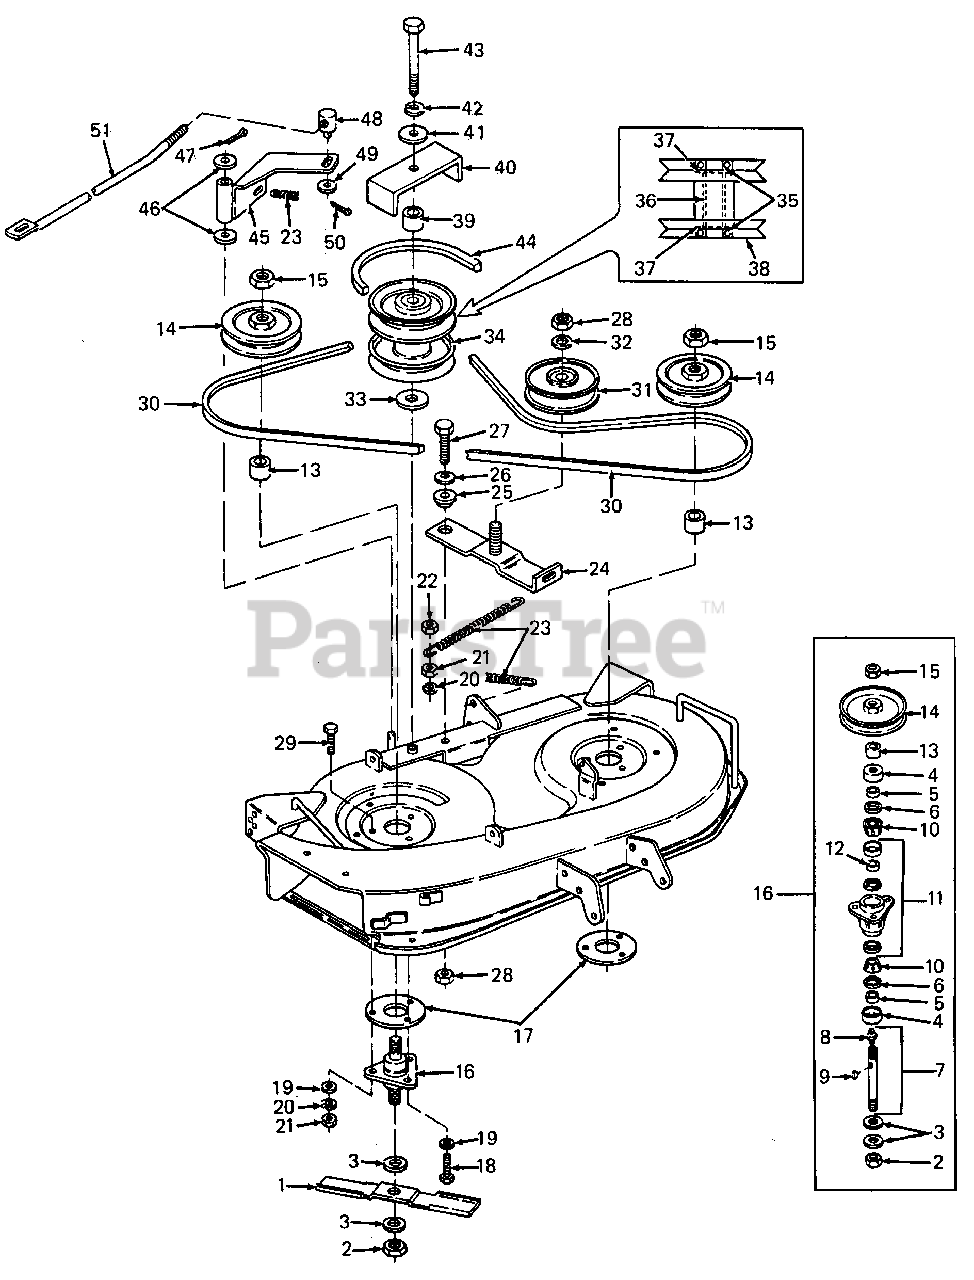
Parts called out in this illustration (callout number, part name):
1	Blade, Low Lift, 16.28 Lg
2	Nut, Hex, 3/4-16 GR8
3	Washer, Flat, .781 X 2.0 X .105 Thk HDN
4	Cup, Spindle HDN
5	Spacer, .755 X 1.25 X .44 Lg
6	Seal, Oil, 1.25 X 1.874 X .25
7	Kit, Spindle w/Seal
8	Fitting, Lube, 3/16 Drive
9	Key, #91 Woodruff, 1/4 X 3/4 HDN
10	Cone, Bearing
11	Housing, Spindle w/Cups
12	Spacer, Bearing
13	Spacer, .75 X 1.38 X .56 Lg
14	4L V-Pulley, 4.62 OD X .75 ID
15	Nut, Hex Jam, 3/4-16 GR5
16	Spindle Service Kit
17	Plate, Spindle Mounting
18	Screw, Hex Cap, 3/8-16 X 1.75 Lg GR5
19	Washer, Flat, .378 X 1.0 X .127 Thk
20	Washer, Lock, 3/8
21	Nut, Hex, 3/8-16 GR5
22	Nut, Hex Center Lock Jam, 3/8-16
23	Spring, Extension, .62 OD X 6.12 Lg
24	Bracket, Idler
25	Spacer, Shoulder
26	Washer, Bell
27	Screw, Hex Cap, 3/8-16 X 1.25 Lg GR5
28	Nut, Hex Center Lock, 3/8-16 GR5
29	Screw, Hex Cap, 3/8-16 X 1.25 Lg GR5
30	V-Belt, 1/2 X 60 Lg, A Full
31	Pulley, Flat Idler, 3.88 OD
32	Washer, Flat, .385 X .88 X .06 Thk HDN
33	Washer, Flat, .63 X 1.0 X .06 Thk HDN
34	Pulley Assy, Double
35	Bearing, Ball, .62 ID X 1.38 OD X .44 Thk
36	Spacer, Pulley, .64 ID X .81 OD X 2.25 Lg
37	Snap Ring, Internal
38	Pulley, Double
39	Spacer, .632 X .875 X .90 Lg
42	Washer, Lock, 5/8
43	Bolt, Hex, 5/8-18 X 5.0 Lg GR5
44	V-Belt, PTO Drive
47	Pin, Cotter, 1/8 Dia X 1.0 Lg
48	Ferrule
49	Washer, Flat, .344 X .875 X .06 Thk
50	Pin, Cotter, 3/32 Dia X .75 Lg
51	Rod, Deck Brake
